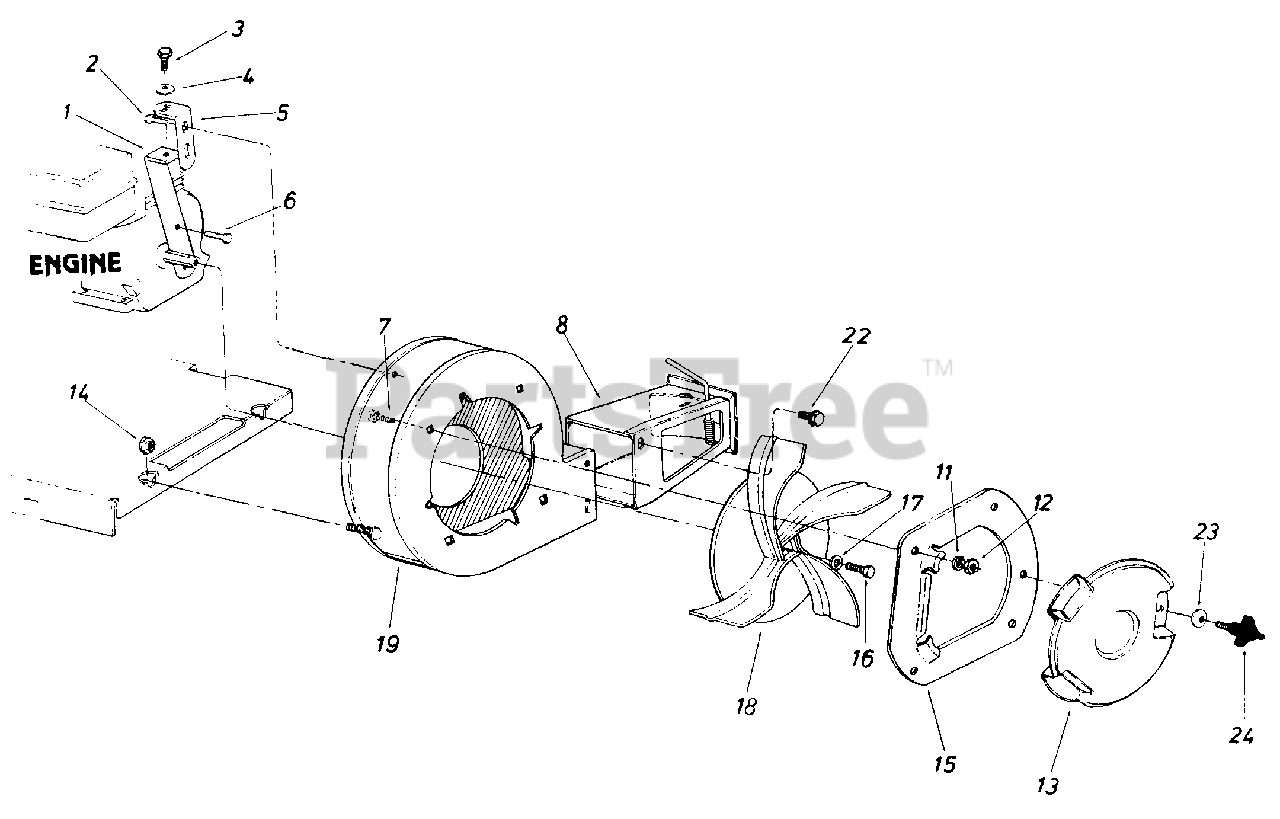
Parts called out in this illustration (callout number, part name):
3	Hex Bolt 5/16-18 x .75" Lg.*
4	L.-Wash. 5/16" I.D.*
7	Carriage Bolt 5/16-18 x .62" Lg.
12	Hex Nut 5/16-18 Thd.*
13	Blower Guard
14	Hex Shoulder Nut .50" I.D.
17	L.-Wash. 3/8" I.D. HD.
18	Air Vane Plate Ass'y.
23	Belleville Wash. .34" I.D. x .87" O.D.
24	3-Arm Thumb Scr. 5/16-18 x .75" Lg.
